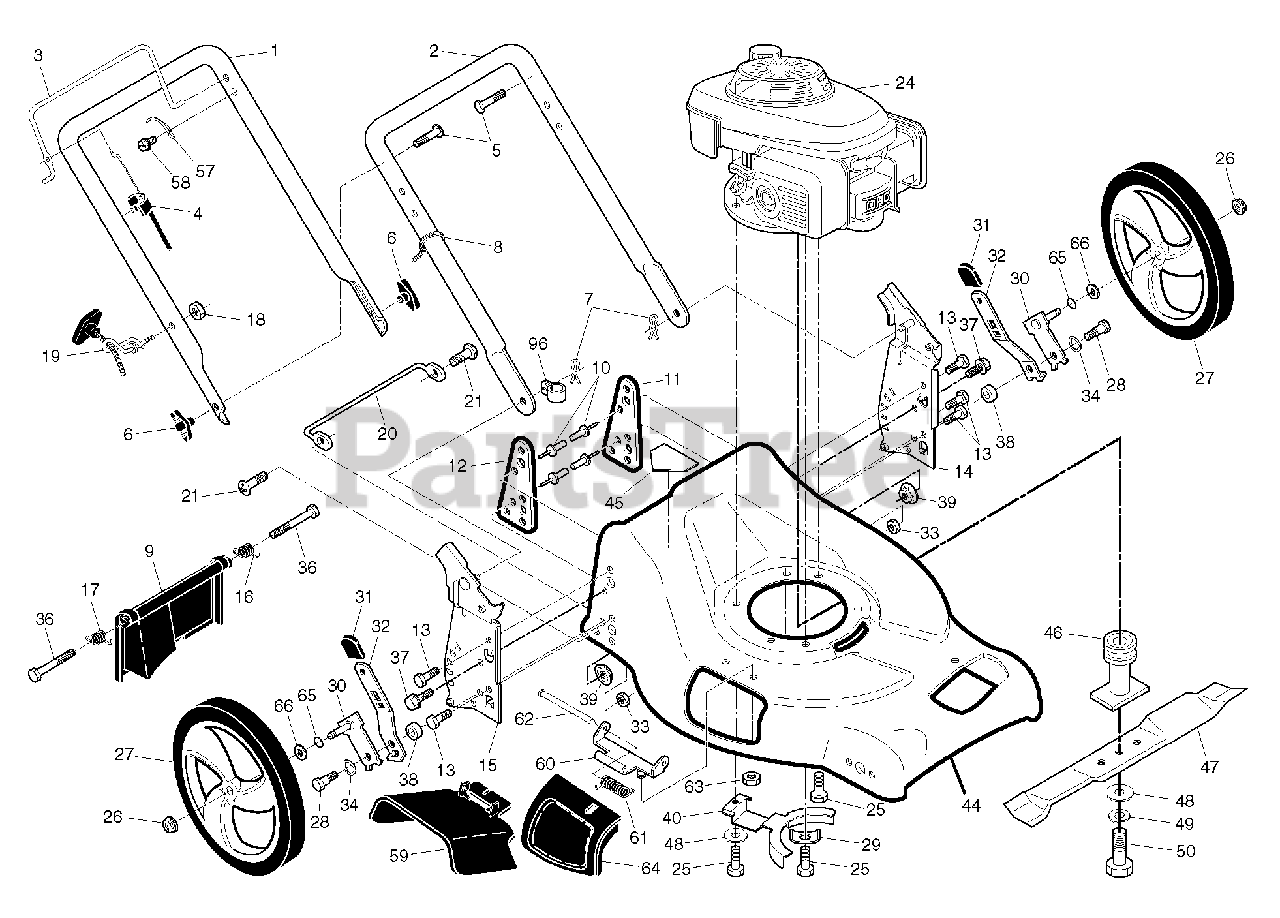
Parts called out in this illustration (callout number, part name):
1	HANDLE.UP.DSTR.EZ.FG/RGD.CREAS
2	HANDLE.LOWER.D-STRAIT.BLACK
3	BAIL.DSTRT.AW.CREAS.BLACK
5	BOLT, HANDLE 5/16-18X1.75
6	KNOB, DEFLECTOR
7	HAIRPIN COTTER
8	TIE GUIDE
9	REAR DOOR ASSEMBLY
11	SUPPORT BRACKET LH
12	BRACKET.SUPRT.RH.21.FWGD
13	SCREW 14-20 X 5/8
14	Handle Bracket Assembly, RH 21 Fgd HW
15	BRACKET.ASM.HNDL.RT.21.FGD.HW
16	SPRING.REAR.DOOR.EZ.21.LT
17	SPRING.REAR.DOOR.EZ.21.RT
18	NUT
19	GUIDE.ROPE.STD.BLK.ZIN
20	FOOT.GUARD.21.DOM/FGD.CE.10
21	SCREW
25	BOLT 3/8-16X1-1/8
26	NUT.HEX.FLANGE.3/8-16.LOCKNUT
27	Wheel, 12 X 1.75 MAG2 RAD3 Gray BB
28	SHOULDER BOLT 5/16-18
29	Engine Washer, Bzp
30	ARM.ASM.AXLE.REAR.5/9.POS.BZP
32	SELECTOR SPRING
33	NUT.71038.31-18.HEX.NYLOCK
37	BOLT
38	SPACER.HEIGHT.ADJUSTER
39	NUT.FLANGE.5/16
40	BRACKET.ENG/BELTKEEPER
45	DECAL.INTERNATIONL.CUTFINGER
46	ADAPTER.BLADE.25MM.VS.LOW.CUT
47	BLADE.21.PUSH
48	WASHER,HARDEN
49	LOCKWASHER
50	SCREW, HEX HD 3/8-24 X 1-3/8
57	BRACKET UPSTOP
59	DISCHARGE DEFLECTOR
60	HINGE BRACKET ASSEMBLY
61	SPRING.TORSION
63	LOCKNUT
64	DOOR.MULCH.21.REAR
65	O-RING..070X.487.NEOPRENE
96	CLIP.CABLE.BLK
